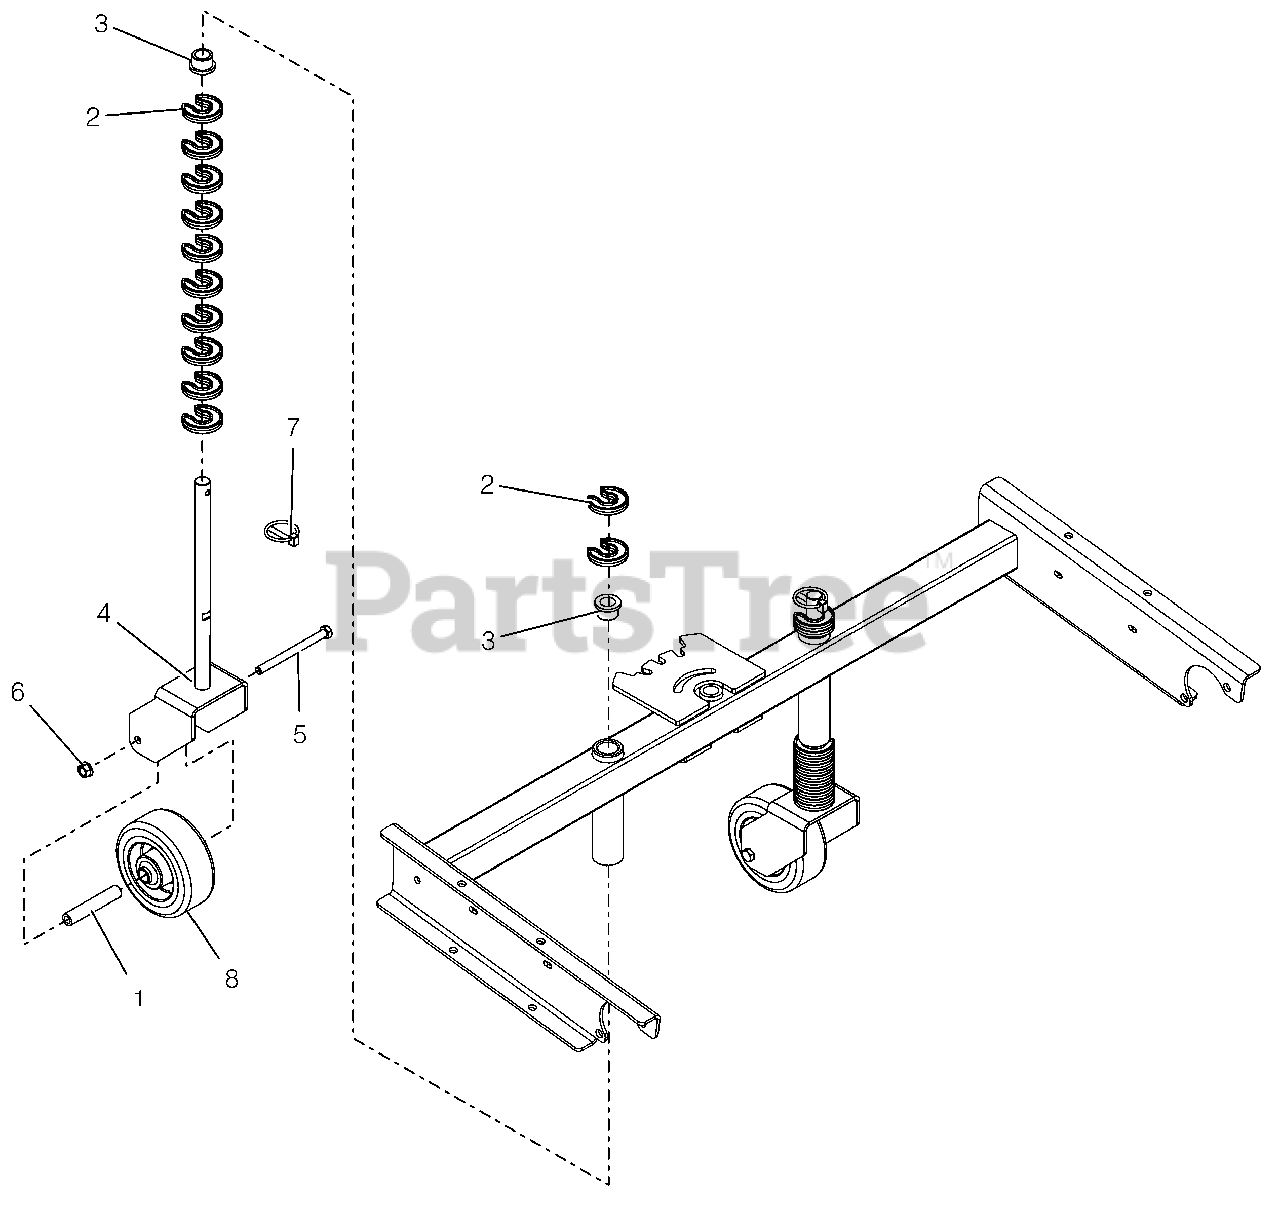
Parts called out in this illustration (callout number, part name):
1	SPACER, CASTER WHEEL
2	CLIP-HOC FIXED
3	BUSHING, FLANGE .75X.75X1.0
4	FORK, CASTER
5	@BLT-HEX .38-16X4.50 GR5 YWZC
6	@NUT-LK-TOP-FLG .38-16 YWZC
7	PIN, 1/4X1-9/16 LYNCH
8	WHEEL, CASTER - 5"OD
